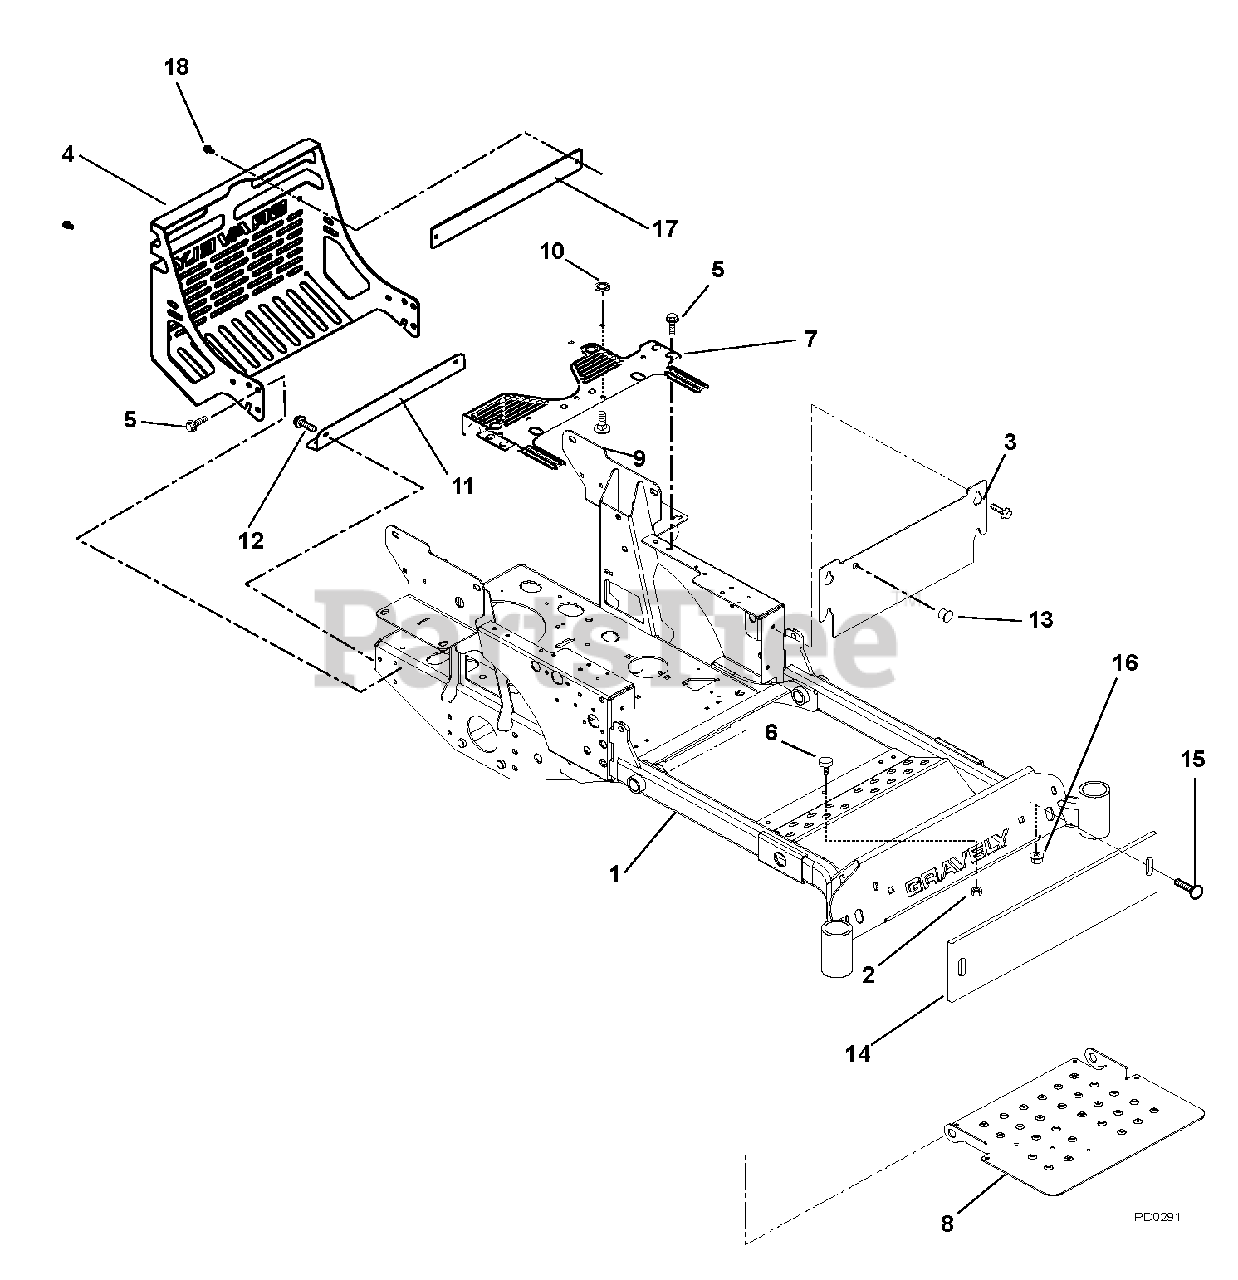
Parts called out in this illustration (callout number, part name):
1	Frame, Compact-Z
2	Nut, Spin Lock Flange .312-18
3	Access Panel
4	Bumper, Rear
5	Screw, Tapping .38-16 x .75 Hex Washer Head
6	Bumper, Rubber
7	Seat Support
8	Panel, Inspection
9	Bolt, Round Head Square Short Neck .31-18 x .75 Grade 5
10	Nut, Push .312
11	Heat Shield
12	Screw, Tapping .38-16 x .50 Hex Washer Head
13	Plug, Hole .56
14	Counterwieght CZ Front – Black
15	Bolt, Round Head Square Neck .50-13 x 2.50 Grade 5
16	Nut .50-13 Nyloc Flange
17	Plate, Bumper
18	Screw, Tapping .25-20 x .50 Hex Washer Head
19	Bracket, Mounting Right Hand
20	Bracket, Mounting Left Hand
21	Screw, Tapping .25-20 x .50 Hex Washer Head
